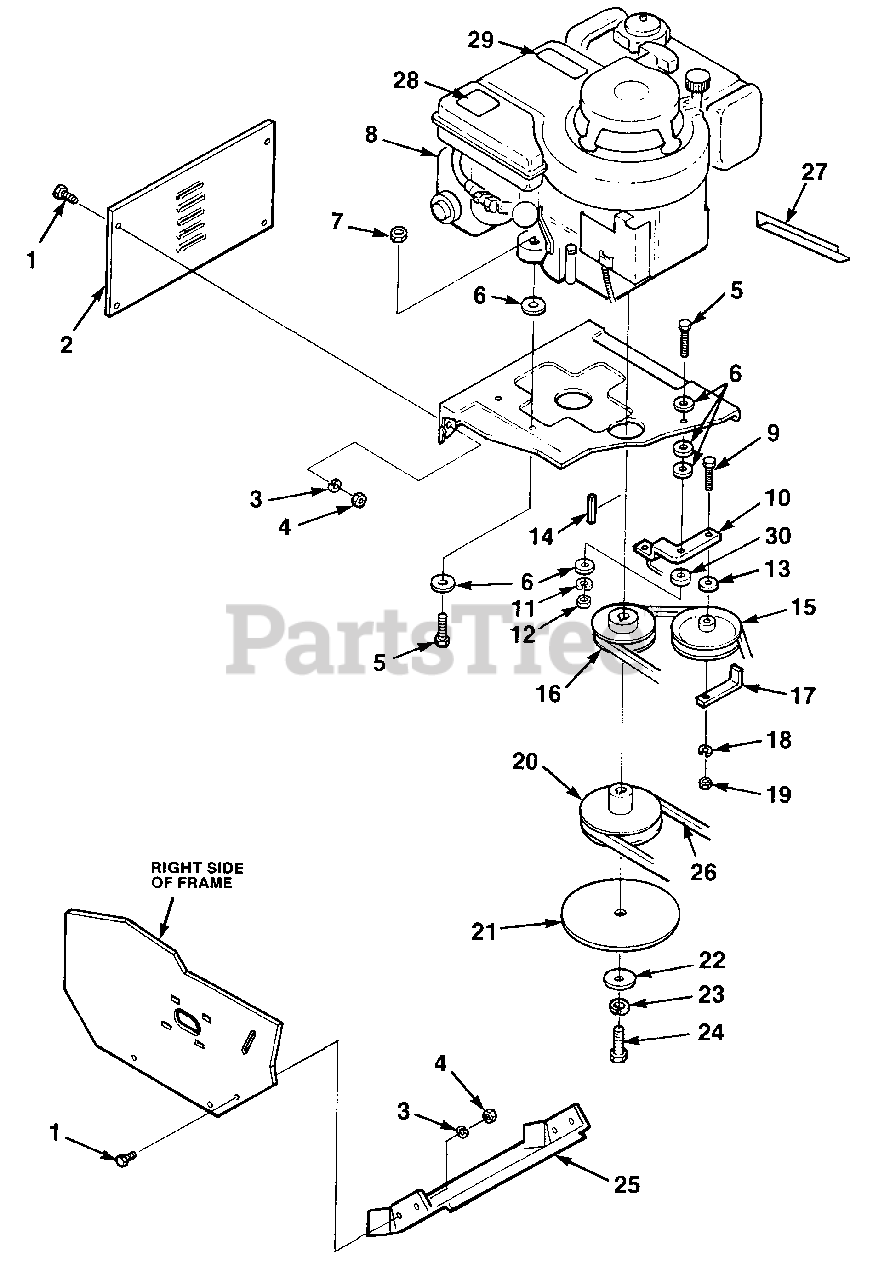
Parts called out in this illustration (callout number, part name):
1	BOLT- Hex centerlock 1/4-20 x.625
2	PANEL- Rear
3	WASHER- Lock 1/4"
4	NUT- Hex 1/4-20
5	SCREW- Hex centerlock 5/16-18 x 1 1/2"
6	WASHER- Engine
7	NUT- Hex centerlock 5/16-18
8	ENGINE- 8 H.P.
9	SCREW- Hex centerlock 3/8-16 x 2 1/4"
10	ARM- Idler
11	WASHER- Lock 5/16"
12	NUT- Hex centerlock 5/16-18
13	WASHER- Plain 3/8"
15	PULLEY- Idler
16	PULLEY- Traction
17	GUIDE- Belt
18	WASHER- Lock 1/4"
19	NUT- Hex centerlock 1/4-20 x 1"
20	PULLEY- Deck
21	DISC- Belt guide
23	WASHER- Lock 7/16"
24	BOLT- Hex centerlock
25	PAN- Bottom
26	BELT- Traction
28	DECAL- Warning
29	DECAL- Warning
